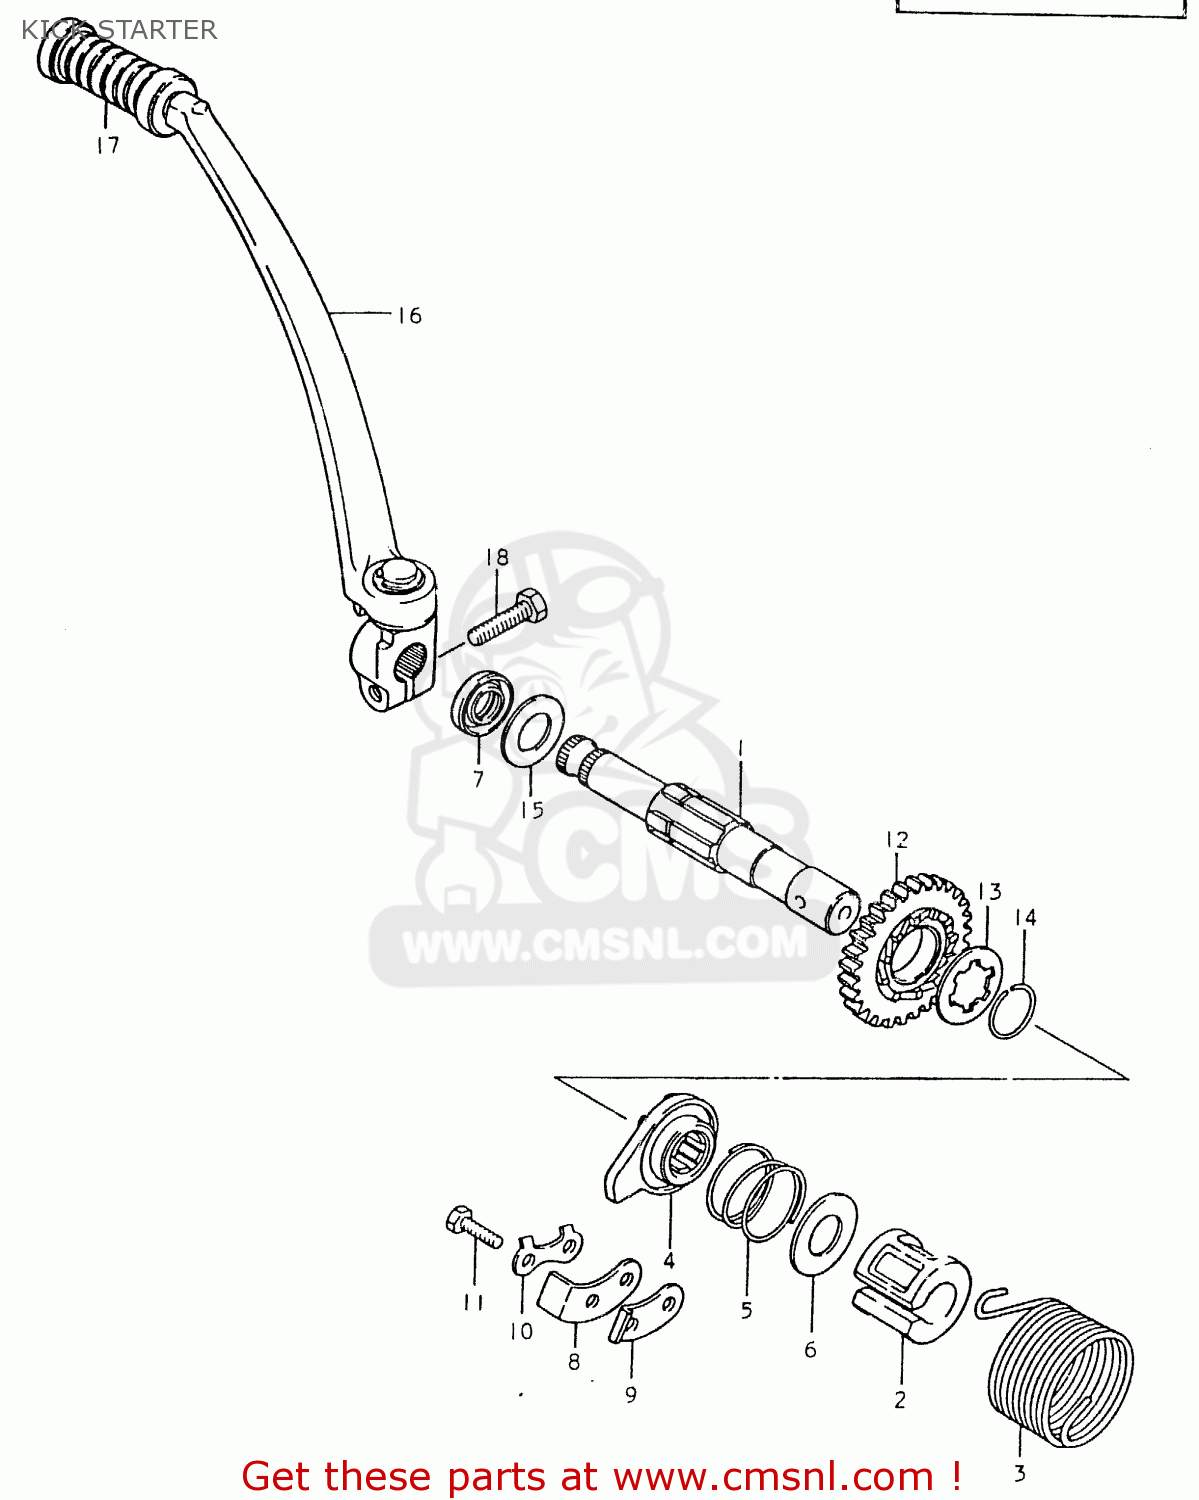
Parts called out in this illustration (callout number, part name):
1	SHAFT,KICK STARTER
2	GUIDE,KICK STARTER SFT SPRING
3	SPRING
4	STARTER,KICK
5	SPRING
6	WASHER
7	SEAL,OIL(16X30X8)
8	GUIDE,KICK STARTER
9	STOPPER,KICK STARTER
10	WASHER
11	BOLT, UPPER
12	GEAR,KICK STARTER DRIVE
13	WASHER,LOCK
14	CIRCLIP
15	WASHER(16X30X1)
16	LEVER ASSEMBLY,KICK STARTER
17	RUBBER,KICK STARTER PEDAL
18	BOLT
